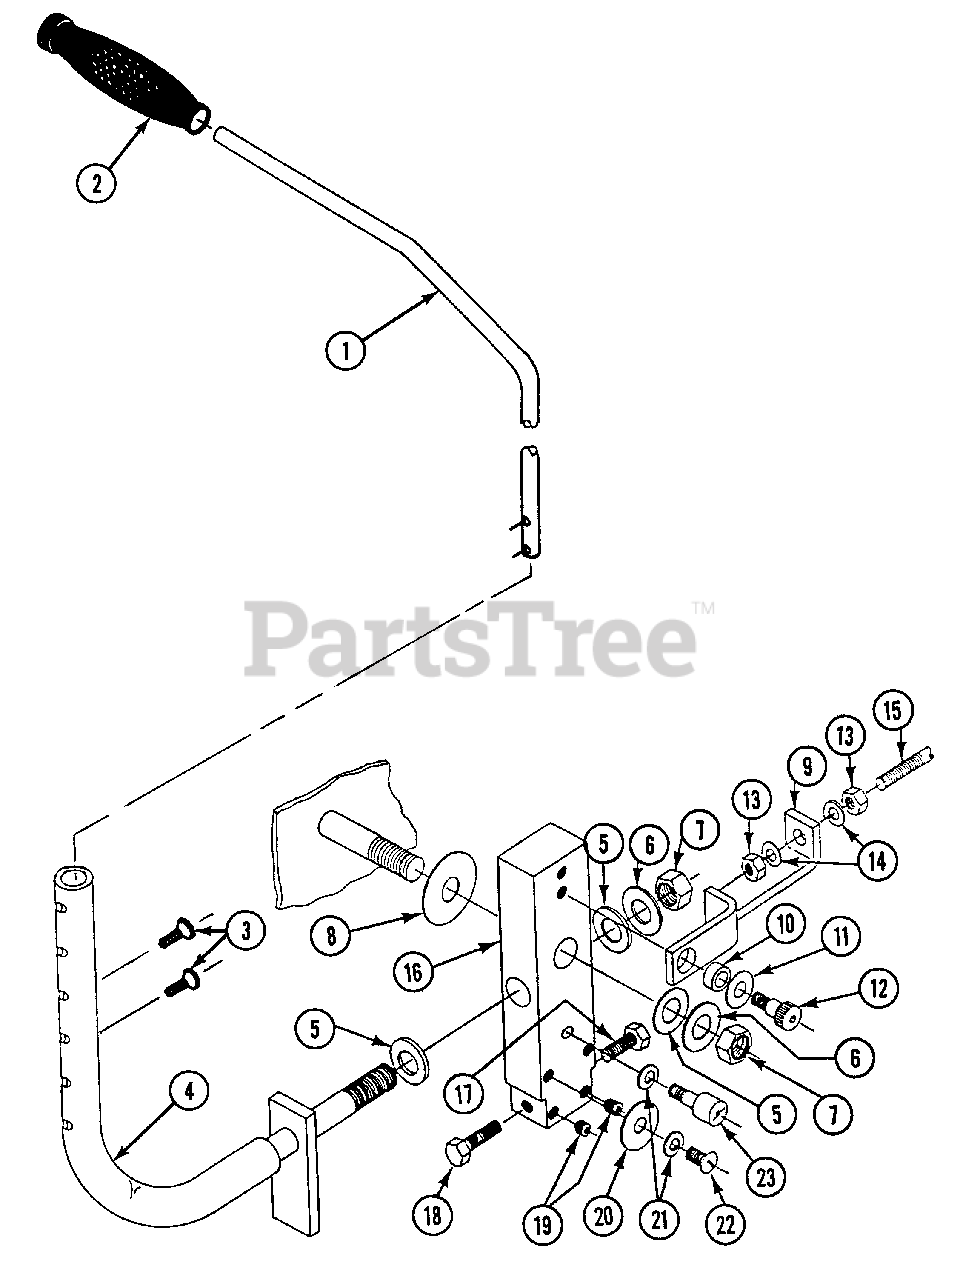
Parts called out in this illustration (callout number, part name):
1	UPPER STEERING HANDLE
2	UPPER HANDLE GRIP
3	SCREW, HANDLE MOUNTING, 1/4-20 X 7/8
4	LOWER ARM WELDMENT
5	WASHER, NYLON, 1/2 ID X 1 OD
6	WASHER, 1/2 NARROW, TYPE B
7	LOCKNUT, HEX, 1/2-20 W/NYLOC
8	WASHER, NYLON, 1-1/2 OD
9	CABLE MOUNTING-CLIP WELDMENT,
10	BUSHINGS BRONZE, 5/16 ID X 1/4 LONG
11	WASHER, THRUST, 5/16 ID X 1/32 THK
12	BOLT, STRIPPER, 1/4-20 X 3/4
13	NUT, HEX, 1/4-28 (COMES WITH #15)
14	LOCKWASHER, 1/4 STD, SPLIT SPRING
15	CABLE, PUSH/PULL, SERIES 40
16	ROTARY MOUNT BLOCK
17	CAPSCREW, HEX, 1/4-28 X 1/2
18	CAPSCREW, HEX, 1/4-28 X 1-1/4
19	SETSCREW, SCKHD, 1/4-20 X 1/4, NYLON TIP
20	WASHER, 1/4 WIDE, TYPE B
21	LOCKWASHER, 1/4 STD, SPLIT SPRING
22	SCREW, SLOTTED ROUNDHEAD 1/4-28 X 1/2
23	CAM FOLLOWER, 5/8 DIA
